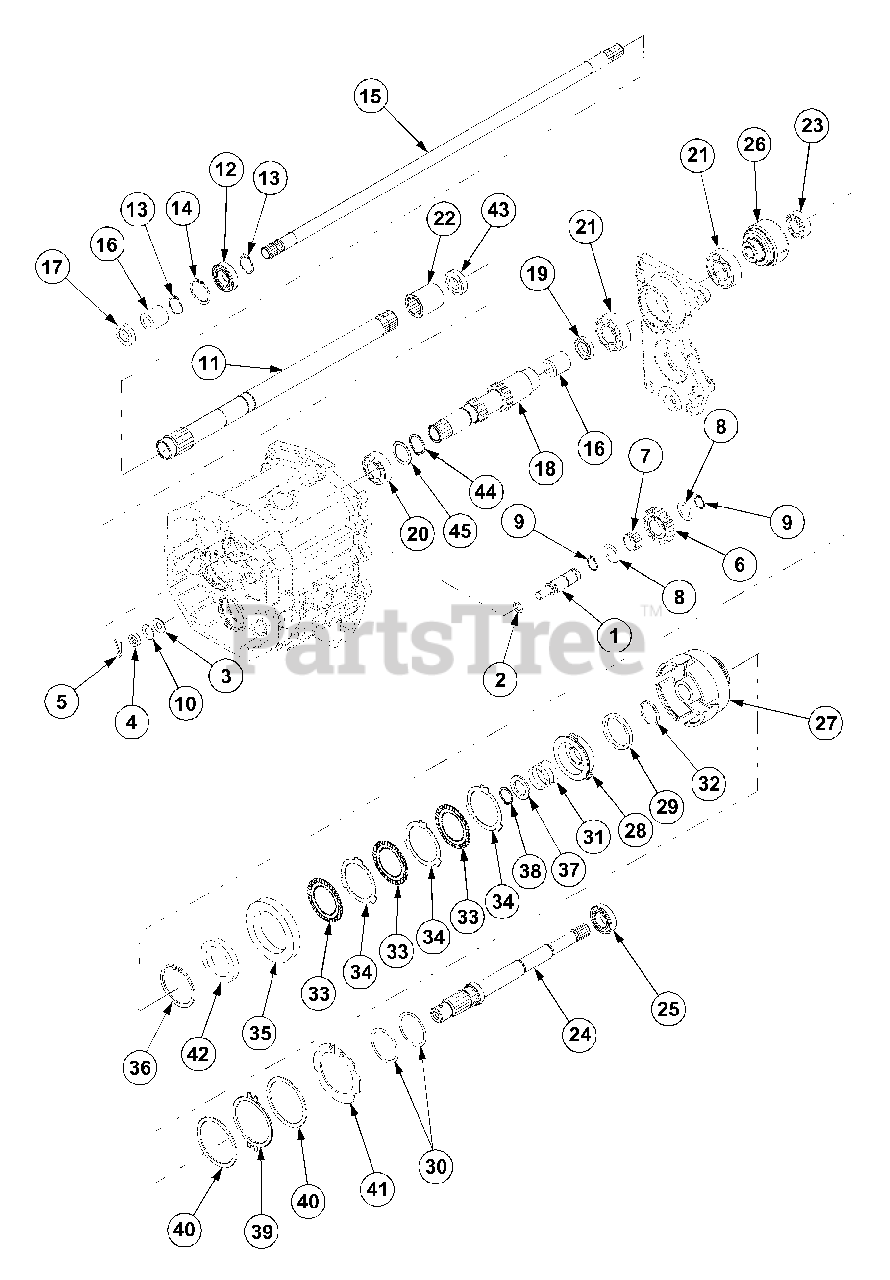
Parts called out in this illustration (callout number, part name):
1	Shaft, Back Idle
6	Gear 22T - Before S/N10398
7	Bearing, Needle
8	Liner B, Thrust
10	Liner
12	Bearing, Ball
13	C-ring
18	Shaft, Shuttle
20	Bearing, ball
21	Bearing, Ball
23	Bearing, Ball
25	Bearing, Ball
27	Case - Model 7530 Before S/N 10138 (C00175)
27	Case - Model 7530 S/N10138 & after
28	Piston - Model 7530 Before S/N 10138 (C00175)
28	Piston - Model 7530 S/N10138 & after
33	Plate, Drive - Model 7530 Before S/N 10138 (C00175)
33	Plate, Drive - Model 7530 S/N 10138 & after
35	Plate, Back - Model 7530 Before S/N 10138 (C00175)
35	Plate, Back - Model 7530 S/N10138 & after
36	Ring - Model 7530 Before S/N 10138 (C00175)
36	Ring - Model 7530 S/N10138 & after
40	Plate, Brake - Model 7530 Before S/N 10138 (C00175)
40	Plate, Brake - Model 7530 S/N S/N10138 & after
42	Spring, Belleville - Model 7530 before S/N 10138 (C00175)
42	Spring - Model 7530 S/N S/N10138 & after
44	C-Ring
